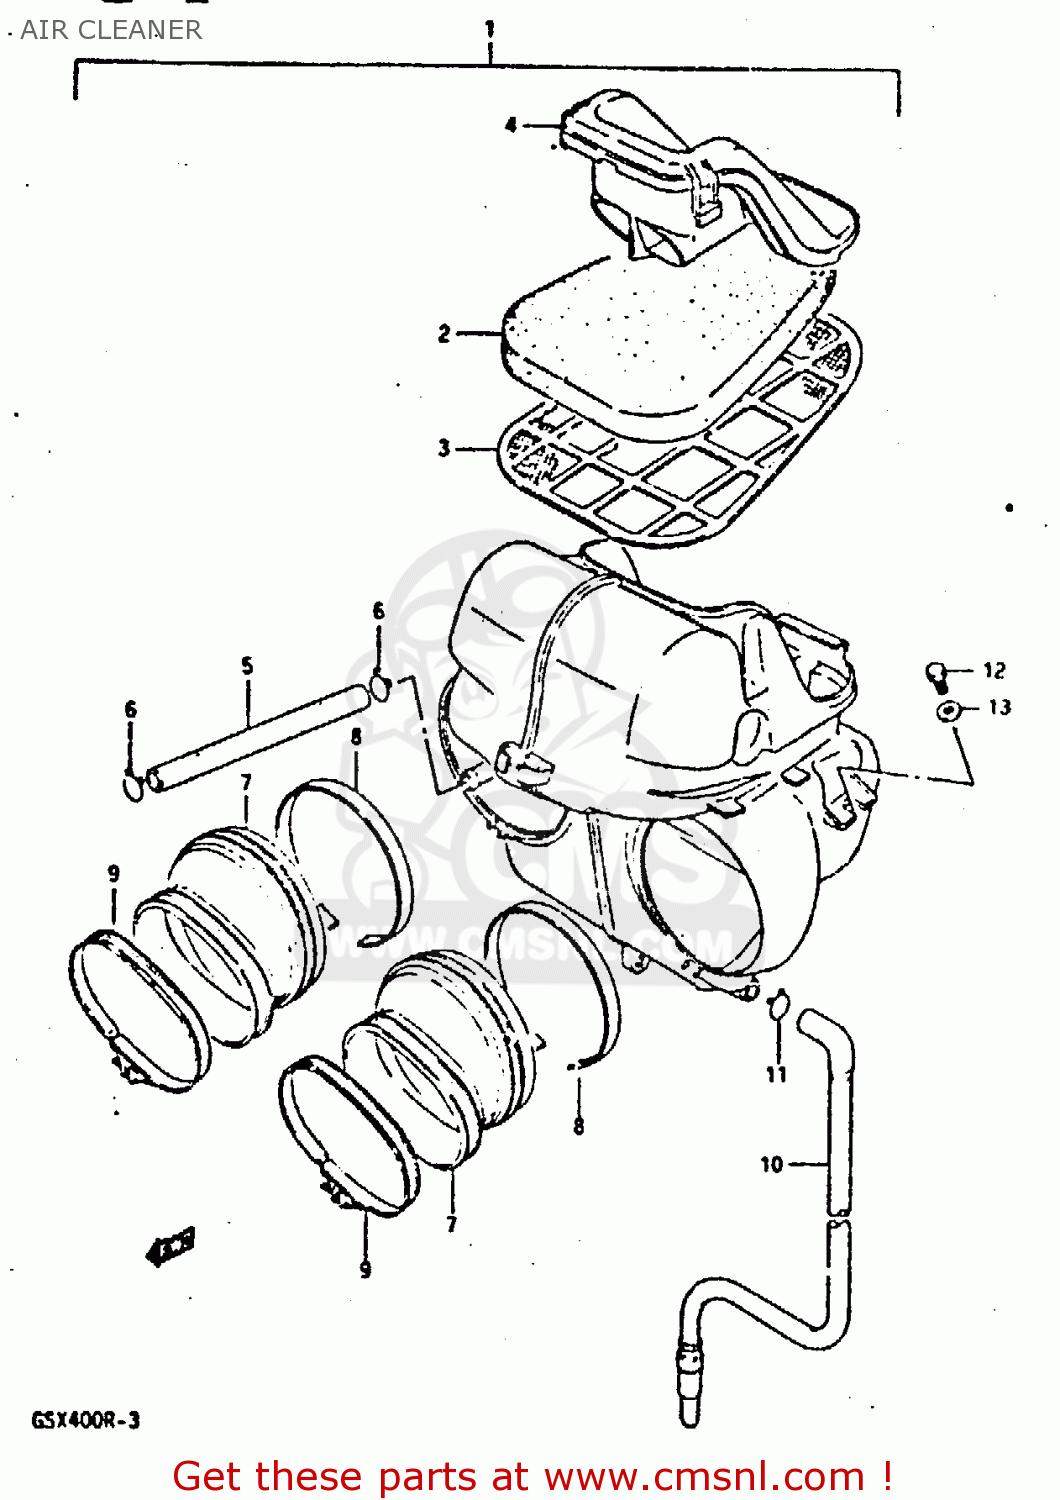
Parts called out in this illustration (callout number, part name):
2	FILTER
4	KAP. L.FILTER
5	TUBE,BREATHER
6	CLIP
7	RUBBER.LUCHTFIL
8	RING
9	CLAMP,CARBURETOR SIDE
10	TUBE,DRAIN
11	CLIP
12	BOLT
13	WASHER
